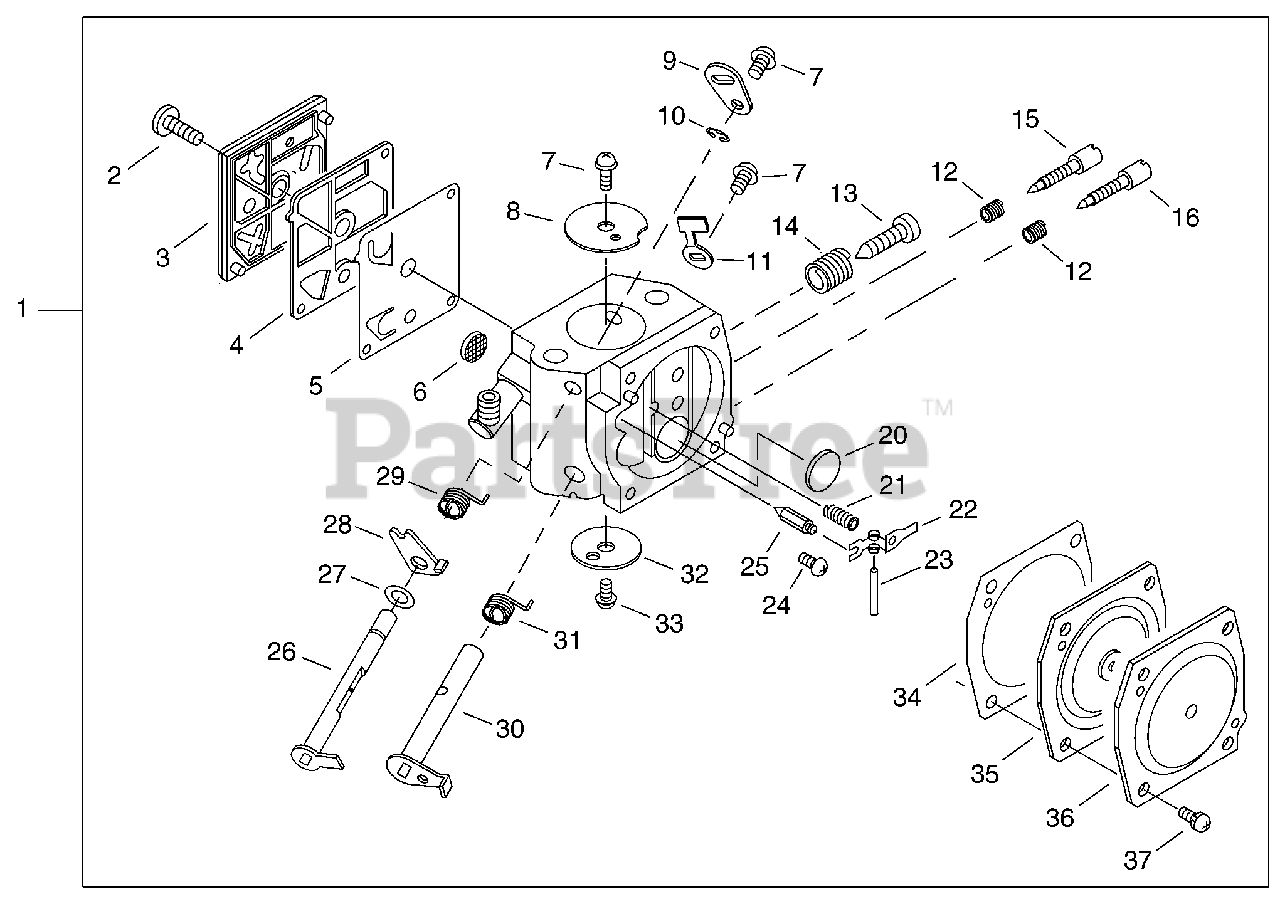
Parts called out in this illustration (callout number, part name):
1	CARBURETOR - HDA-274
3	COVER, FUEL PUMP
4	GASKET, FUEL PUMP
5	DIAPHRAGM, FUEL PUMP
6	SCREEN, FUEL INLET
8	VALVE, THROTTLE
9	LEVER, CHOKE
11	STOP, THROTTLE
12	SPRING, NEEDLE
13	SCREW, IDLE ADJUST
14	SPRING, IDLE ADJUST
15	NEEDLE, HIGH SPEED
16	NEEDLE, IDLE
20	PLUG, WELCH
22	LEVER, METERING
23	PIN, METERING LEVER
24	SCREW, METERING LEVER PIN
25	VALVE, INLET NEEDLE
26	SHAFT, CHOKE
28	LEVER, FAST IDLE
29	SPRING, CHOKE RETURN
30	SHAFT, THROTTLE
31	SPRING, THROTTLE RETURN
32	VALVE, THROTTLE
34	GASKET, METERING DIAPHRAGM
35	DIAPHRAGM, METERING
36	COVER, METERING DIAPHRAGM
